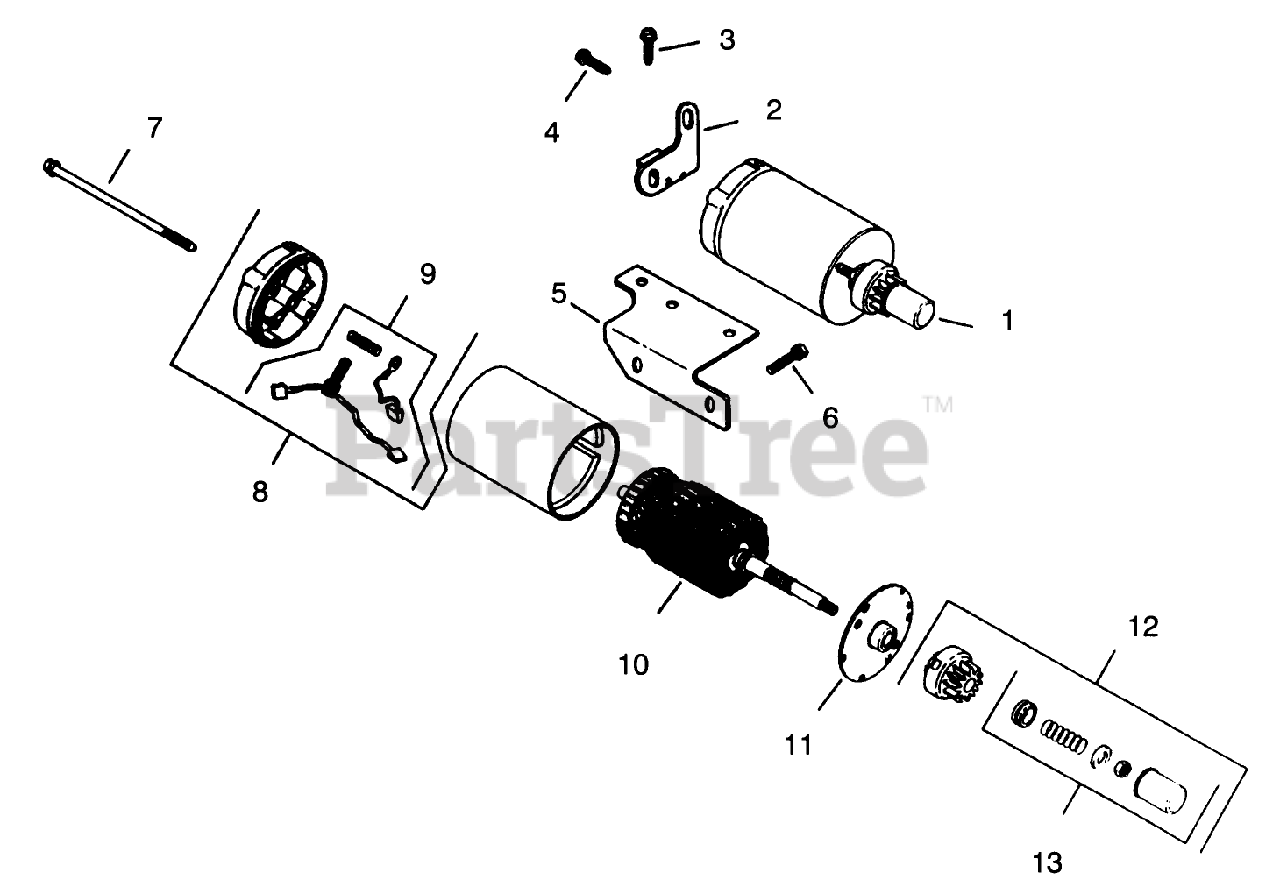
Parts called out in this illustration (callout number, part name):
1	KOHLER 41-098-04
2	KOHLER 45-126-17
3	KOHLER X-67-62
4	KOHLER X-67-83
5	KOHLER 47-126-29
6	KOHLER X-159-2
7	KOHLER 41-086-19
8	KOHLER 41-227-04
9	VNDR #52-755-15
10	KOHLER 47-170-02
11	KOHLER 41-227-03
12	KOHLER 47-755-07
13	KOHLER 47-755-13
